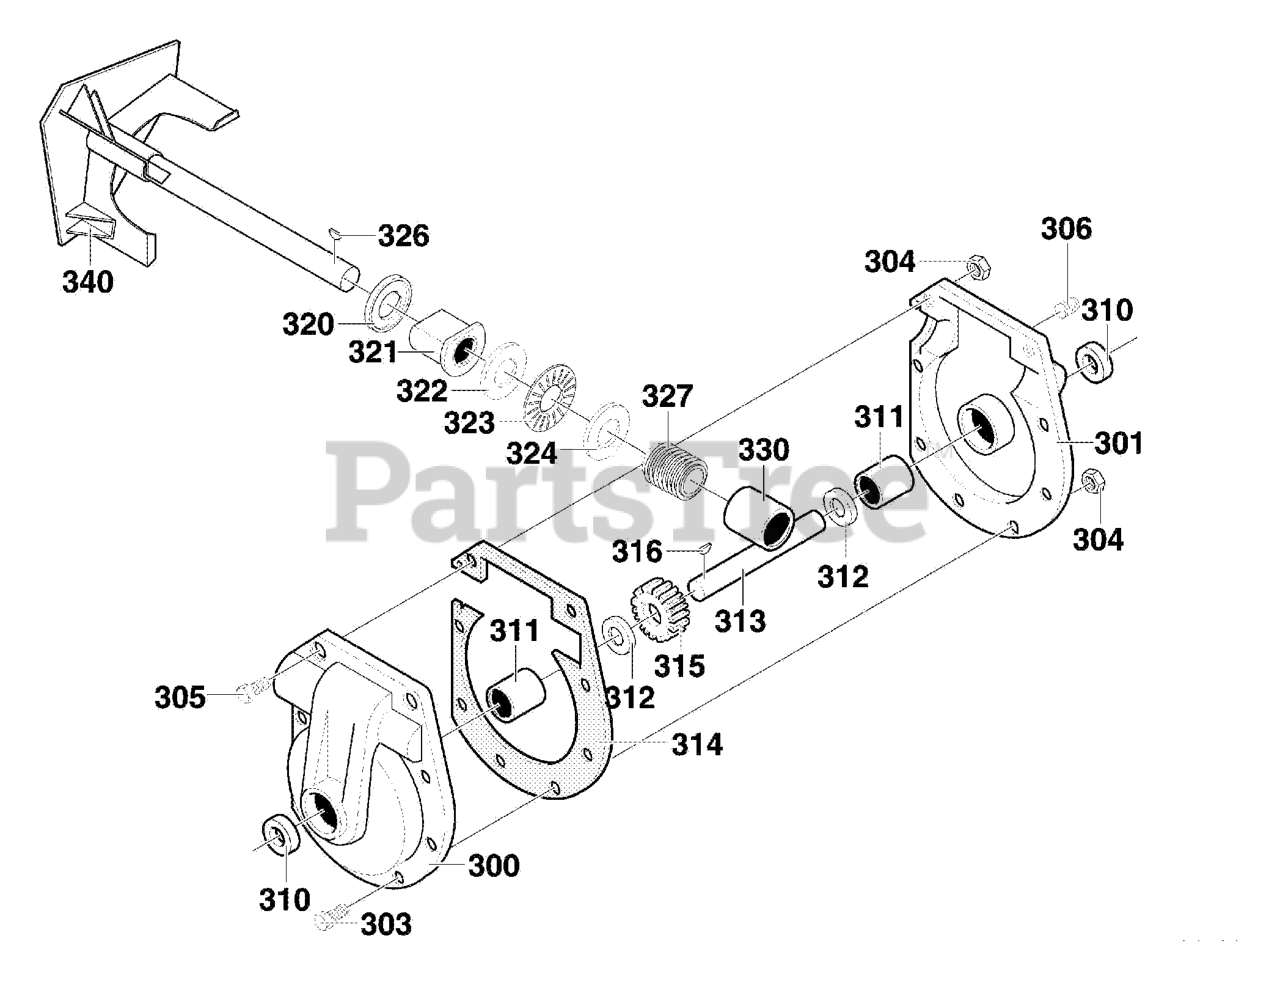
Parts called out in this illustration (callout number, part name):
300	CASE, GEAR RH
301	CASE, GEAR LH
303	SCREW, 5/16-24 x 1.00
304	NUT, 5/16-24 HEXWDFLLK
305	SCREW, 5/16-24 x 1.50
306	PLUG, PIPE
310	SEAL, OIL
311	BEARING, SLEEVE
312	WASHER, FLAT 1.00 x 1.54 x .09
313	SHAFT, AUGER
314	GASKET, GEAR BOX
315	GEAR, WORM
316	KEY, WOODRUFF #91
320	RING, QUAD
321	BEARING, FLANGE
322	WASHER, FLAT .752X1.24X.093
323	BEARING, ROLL
324	WASHER, FLAT .752X1.24X.093
326	KEY, HI-PRO #606
327	GEAR, WORM
330	BEARING
